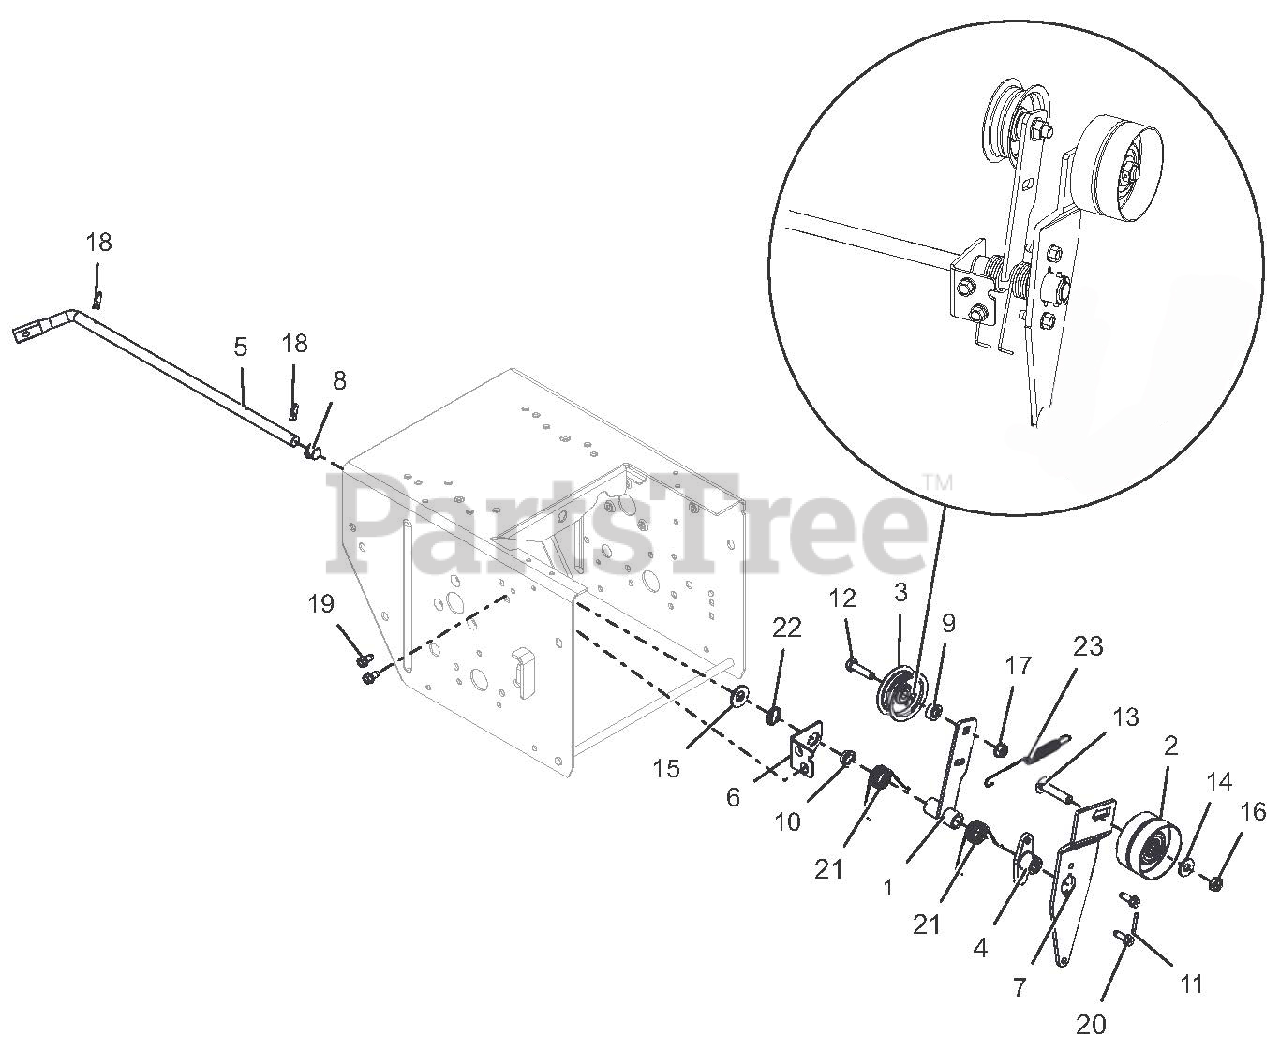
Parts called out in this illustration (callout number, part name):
1	ARM, IDLER -TRACTION (BLACK)
2	IDLER, FLAT -2.75 OD X .375 ID
3	IDLER, FLAT - 2.00"
4	HUB, BRAKE ARM
5	ARM, ATTACHMENT-BLACK
6	BRKT, SUPPORT
7	ARM, IDLER ATTACHMENT
8	BUSHING, POLYLINER - .50 SPLIT
9	SPCR, FLANGE .315X.0500X.358X.281
10	BSHG, FLANGE .500 x .625 x .270 x .750
11	PIN, ROLL .125 X 1.00
12	BLT-HEX .31-18X1.25 GR5 YWZC
13	BLT-RHDSSQNK .38-16X1.75 G5YZ
14	WSHR-FL-STL.38X.875X.083 YWZC
15	WSHR-FL-STL.531X1.06X.095YWZC
16	@NUT-LK-CTR-JAM .375-16 YWZC
17	NUT, LK-TOP-FLG .312-18 YWZC
18	CLIP, SPRING
19	SCR-TAP .25-20X.50 HWH TR YWZ
20	SCR-TAP .25-20X.75 HWH TR YWZ
21	SPRG, TORSION
22	WAVE, SPRING .600x.875x.25FH
23	SPRG, EXTENSION
